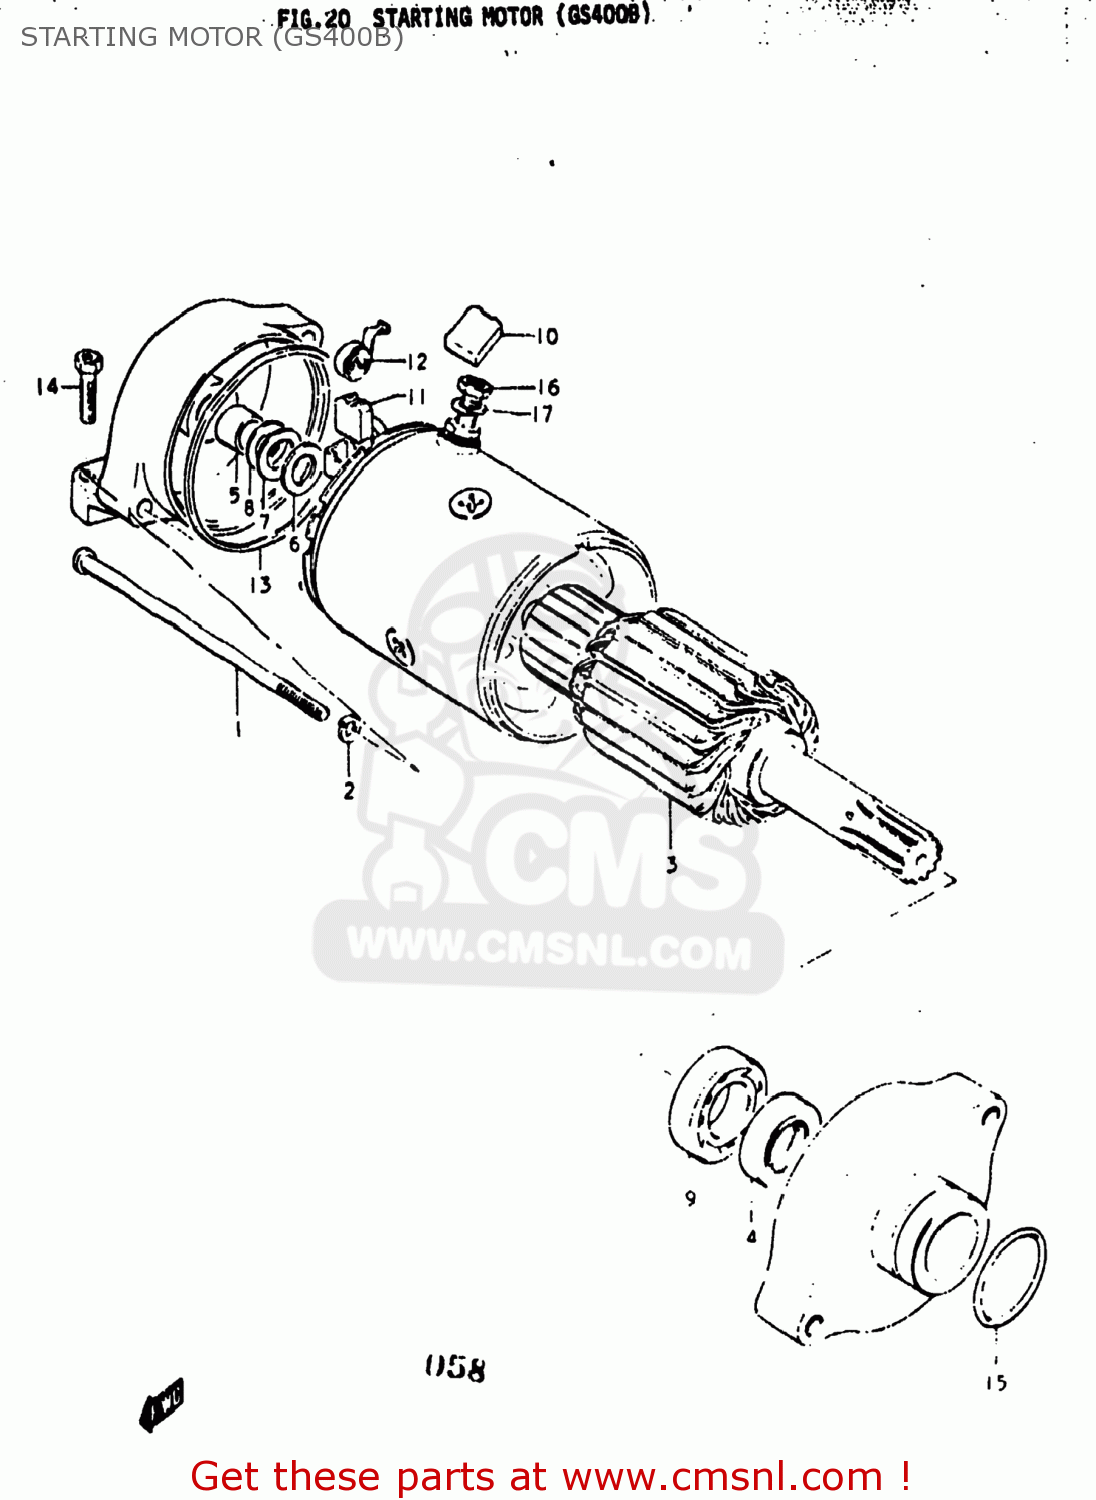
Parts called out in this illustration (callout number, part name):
1	BOLT
2	LOCK WASHER
3	ARMATURE
4	SEAL,OIL
5	BUSHING
6	SHIM, (1)
7	SHIM, (2)
8	SHIM, (3)
9	BEARING
10	BRUSH(-)
11	BRUSH(-)
12	SPRING
13	GASKET
14	SCREW
15	O RING(D:2,ID:24.5)
16	NUT
17	LOCK WASHER
